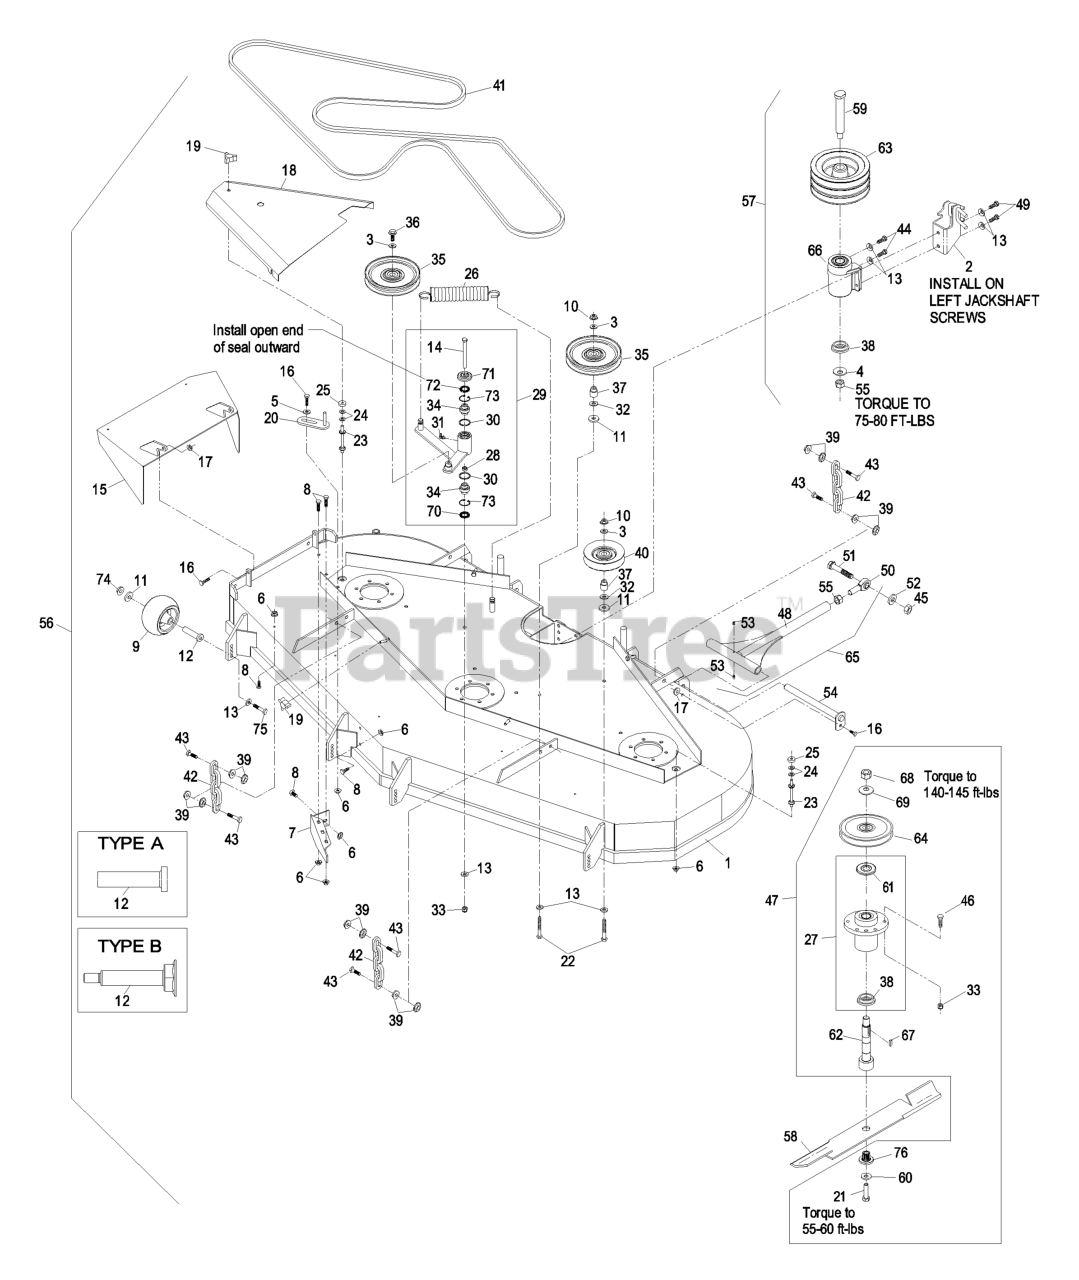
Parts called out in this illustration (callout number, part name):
1	ASM,DECK W/DECALS LZ/XP72
3	WASHER-FLAT
4	WASHER-SPRING
5	WASHER-SPRING
7	WLD,BAFFLE DISCHARGE
8	SCREW-HH
9	ROLLER-SCALP, ANTI
10	NUT-HHF, WHIZ
12	BUSHING-ROLLER
13	WASHER-BELLEVILLE
14	SCREW-HH
15	WLD,CHUTE 72
16	SCREW-HH
17	NUT-LOCK, NI
18	SHIELD,BELT RH
19	KNOB-3 PRONG
20	GUIDE-BELT
21	SCREW-HH
22	SCREW-HH
23	STUD-SHIELD, BELT (SHORT)
24	WASHER-FLAT
27	KIT, CUTTER HOUSING
29	KIT,DECK IDLER LZ/XP
31	FITTING-GREASE, 90 DEG
32	WASHER-FLAT
33	NUT-LOCK, NI
34	BEARING-SPHERICAL
36	SCREW-HHF
37	BUSHING-IDLER
38	SPACER-GUARD, BOTTOM
40	PULLEY-IDLER
41	BELT-V
42	CHAIN-LIFT, DECK
43	SCREW-HH
44	SCREW-HH
45	NUT-HEX
46	SCREW-HH
47	ASM, CUTTER HSG COMP 72
49	SCREW-HH
50	BALLJOINT-SPHERICAL
51	SCREW-HH
52	WASHER-LOCK
53	FITTING-GREASE
54	PIN-STRUT
55	NUT-HEX
56	Complete Deck Assy
57	ASM,JACKSHAFT
59	JACKSHAFT
60	WASHER-SPRING
61	GUARD-BEARING, TOP
62	KIT, SPLINED SPINDLE 103-
63	SHEAVE-JACKSHAFT
64	SHEAVE,BLADE DRIVE 7.5
65	STRUT WLDMT S/A
68	NUT-HH
70	SEAL-LIP, DOUBLE
71	GUARD-TOP
72	SEAL-LIP, SINGLE
73	RING-SNAP
74	NUT-HHF, WHIZ
75	SCREW-HH
76	BUSHING,SPLINED
